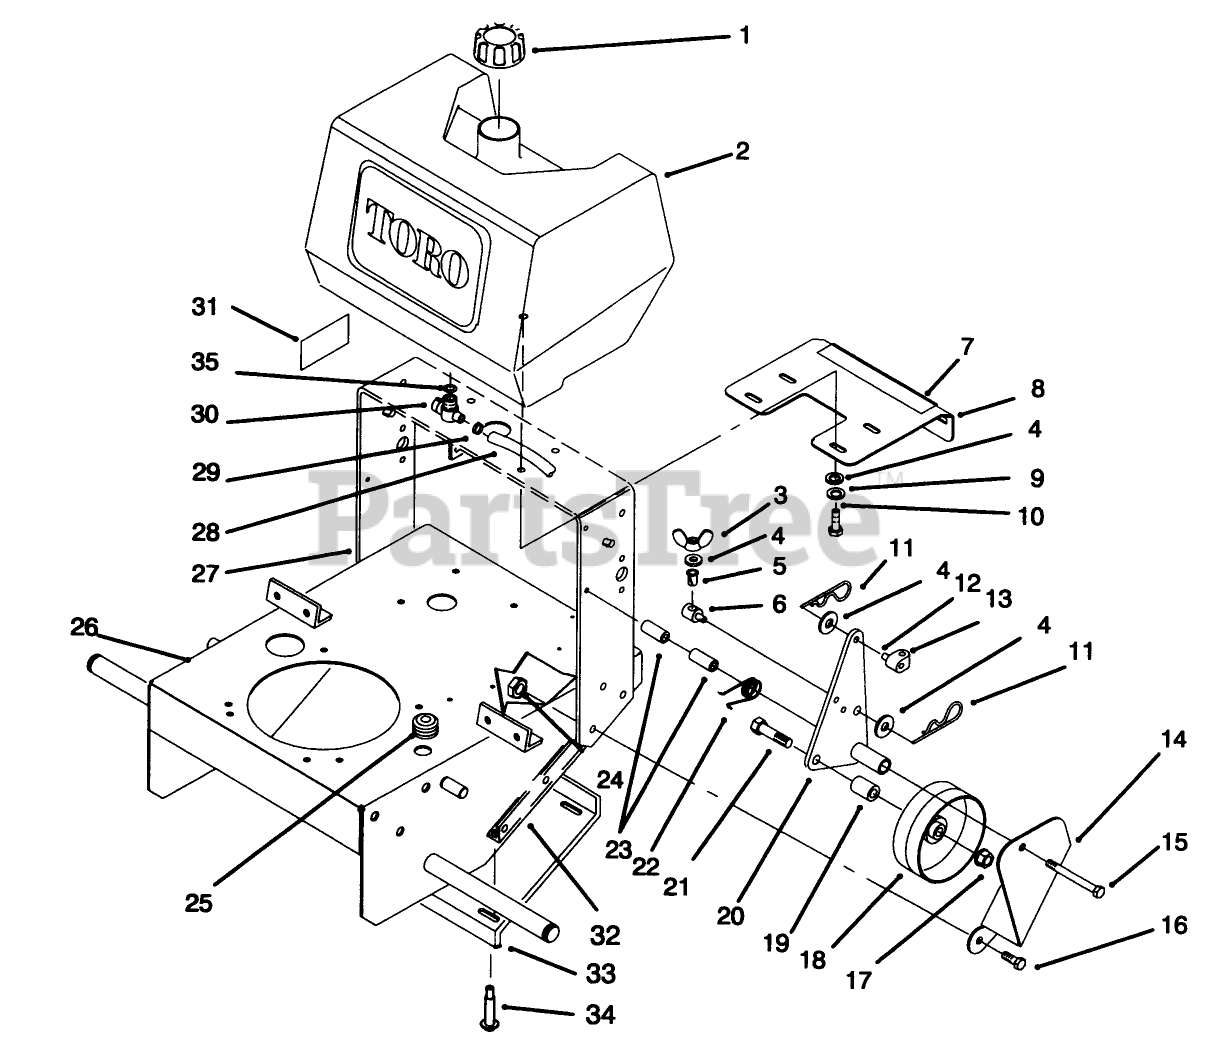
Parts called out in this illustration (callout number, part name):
1	GAS CAP ASM
2	FUEL TANK
3	NUT-WING
4	WASHER-PLAIN
5	BUSHING-NYLON
6	FITTING-ROD
7	DECAL - GROUND SPEED
8	Plate
9	WASHER-LOCK
10	SCREW-HH
11	PIN-COTTER
12	PIN-CLEVIS
13	FITTING-ROD
14	Bracket-LH
15	SCREW-HH
16	SCREW-HH
17	NUT-LOCK, NI
18	IdlerWheel
19	WHEEL IDLER SPACER
20	BRACKET-Idler, LH
21	SCREW-LEVELER
22	SPRING-TORSION, LH
23	SPACER-PIVOT, IDLER
24	NUT-LOCK, NI
25	GROMMET
26	Frame
27	Frame Rear
28	HOSE-FUEL
29	CLAMP-HOSE
30	VALVE-FUEL
31	DECAL-SHUT OFF, FUEL
32	Mount-Angle
33	Panel-Bottom
34	SCREW
35	O-RING
